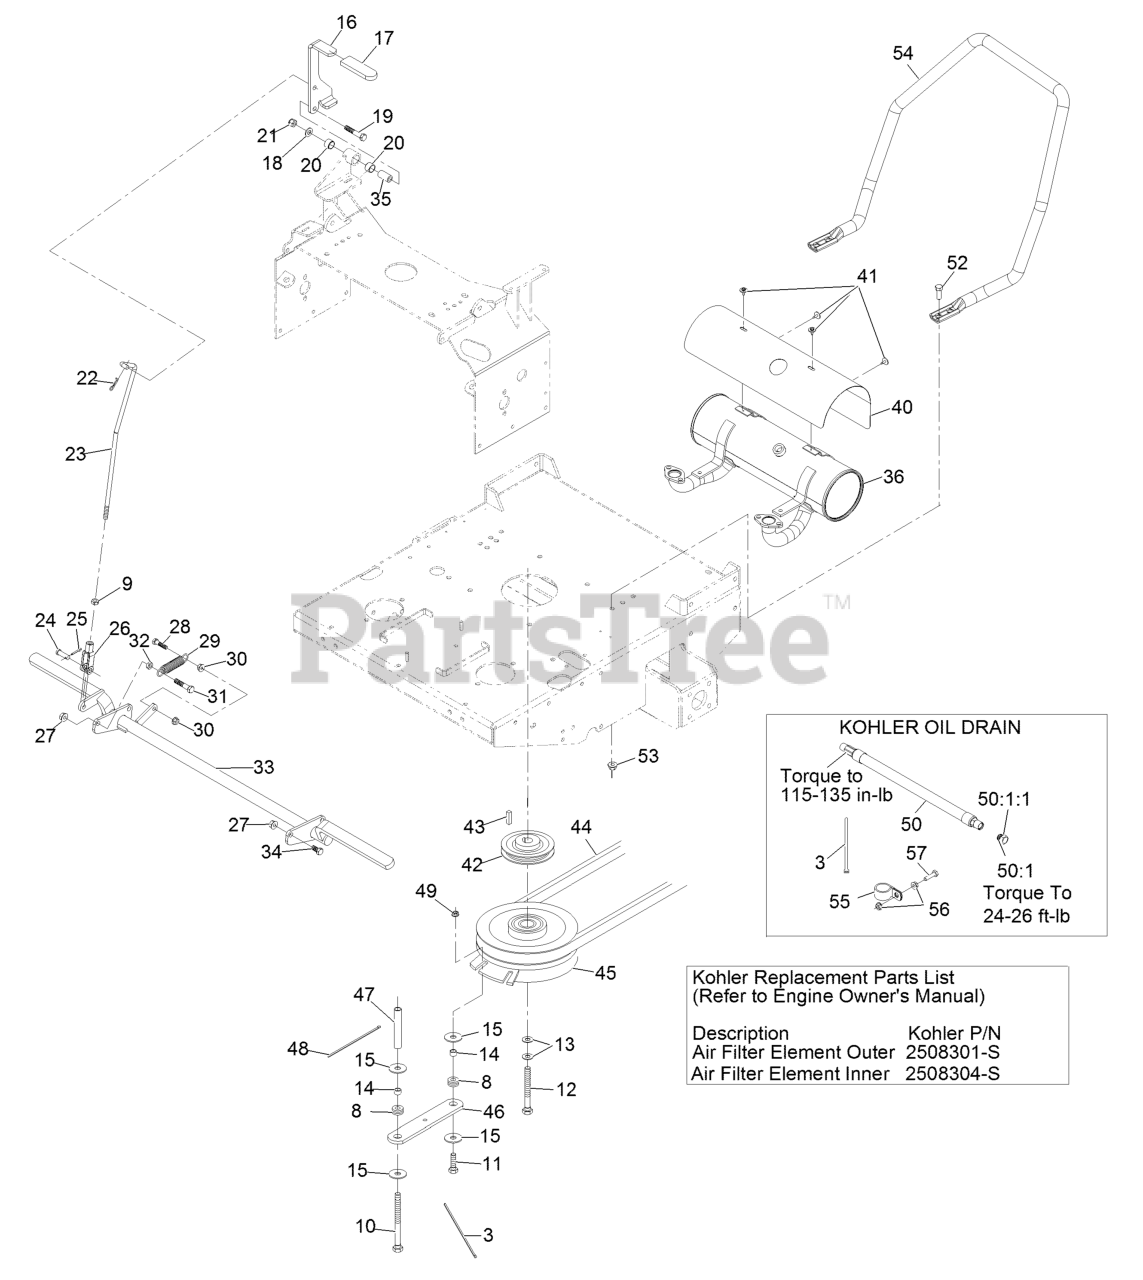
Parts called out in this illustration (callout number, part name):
3	TIE-PLASTIC
8	GROMMET
9	NUT-HJ
10	SCREW-HH
11	SCREW-HH
12	SCREW-HH
13	WASHER-SPRING
16	LEVER,PRK BRK W/DECALS
17	GRIP-LEVER
18	WASHER-FLAT
19	SCREW-HH
20	SLEEVE-BUSHING
21	NUT-LOCK, NI
22	PIN-COTTER
23	LINKAGE, PARK BRAKE
24	PIN-CLEVIS
25	PIN-COTTER
26	YOKE-LINKAGE, BRAKE
27	NUT-HHF, WHIZ
28	SCREW-HH, SPECIAL
29	SPRING-IDLER
31	SCREW-HH
32	NUT-JAM
34	SCREW-HH
35	BUSHING-PIVOT
36	MUFFLER-TTX, EFI
40	SHIELD-MUFFLER,TTX EFI
41	SCREW-HH, THREAD FORMING
42	PULLEY
44	BELT,B 83.65
44	BELT,DECK DRIVE
45	CLUTCH ASM
46	STRAP-CLUTCH, BRAKE
47	SPACER,SHIELD
48	TIE-CABLE
50	OIL DRAIN HOSE ASM
50:1	PLUG-HH
50:1:1	O-RING
52	SCREW-HH
53	NUT-HF, NI
54	GUARD,AIR CLEANER
55	CLIP-LOOM
57	SCREW-HH
